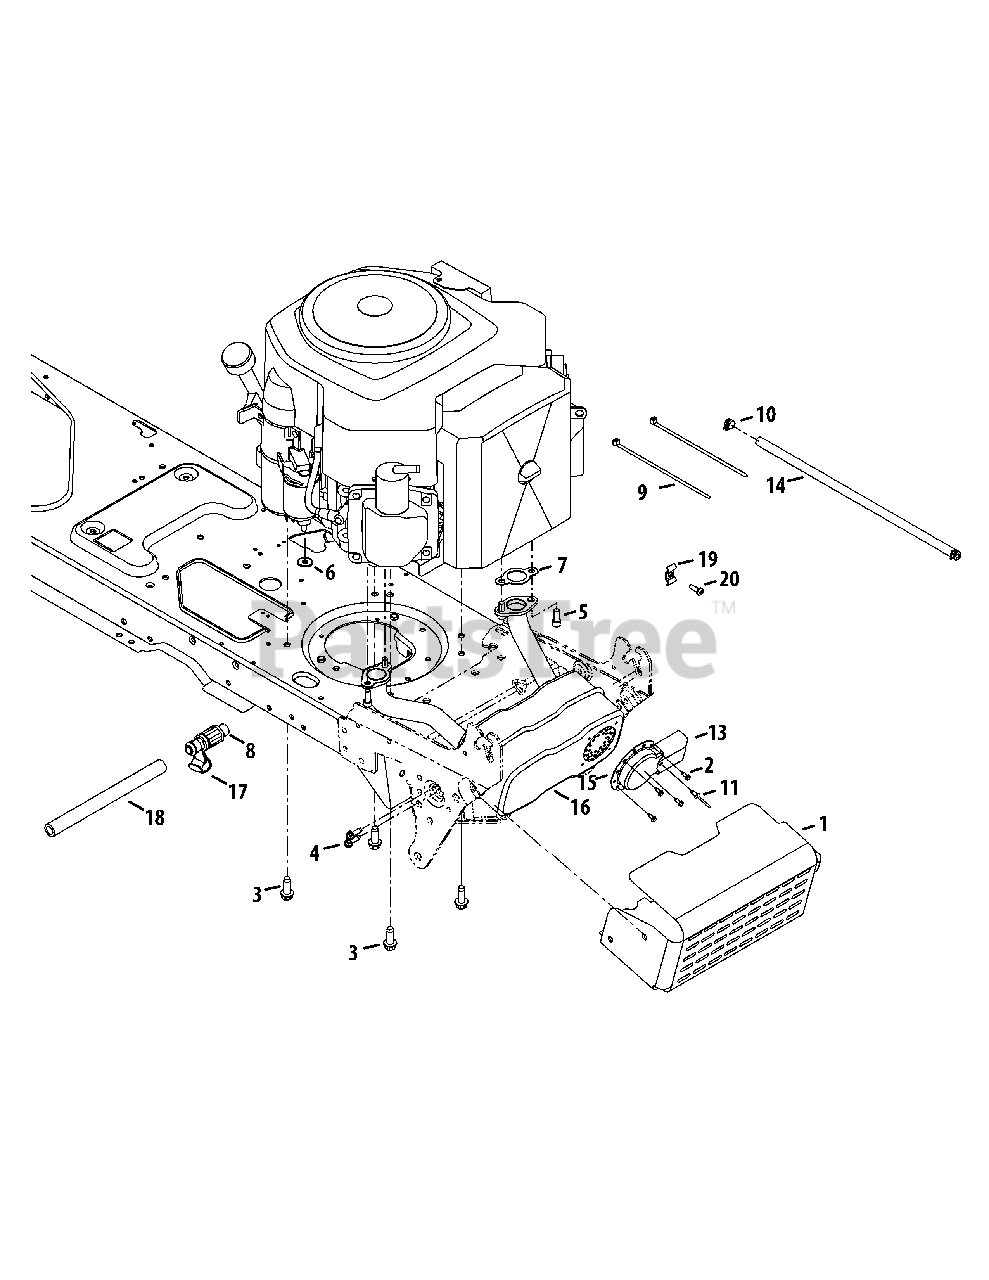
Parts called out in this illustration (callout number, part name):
1	Muffler Shield
2	Hex Wash HD AB S-Tapp Scr #8-.50
3	Hex Wash S-Tapp Scr 3/8-16 x 1.0
4	Thd Forming Scr. 1/4-20 x .75 Lg.
5	Socket HD Cap Scr. 5/16-18 x .75
6	Sems Nut 1/4-20
7	Gasket
8	Sealant: Pipe PST 567 Loctite
11	Rivot, Pop, .188 x .3
13	Muffler Deflector
14	Fuel Hose; Low Permeation, 51" Lg.
15	Muffler Deflector Long
16	Muffler
18	Oil Drain Hose
19	Clamp
20	Torx Tap. Screw M5 x 0.8
